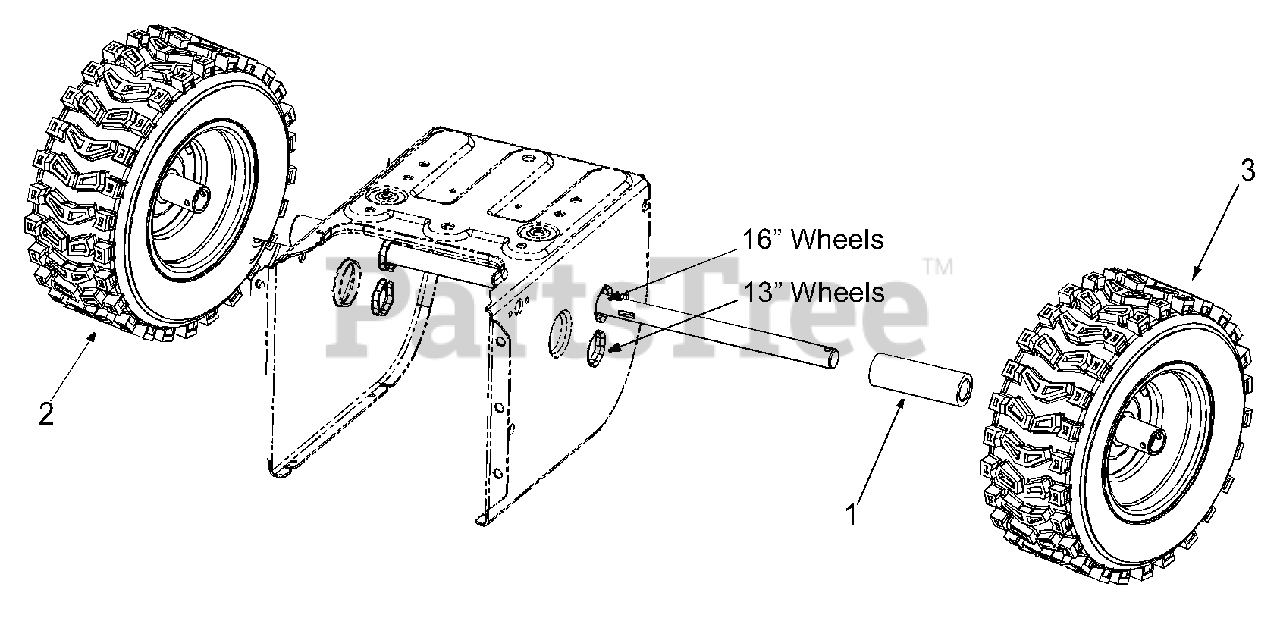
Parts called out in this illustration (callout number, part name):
1	Spacer, Wheel Size: 13 x 5, Model No. 7524
1	Spacer, Wheel Size: 16 x 4.8, Model No. 8526
2	Wheel Comp., Wheel Size: 13 x 5, Model No. 7524
